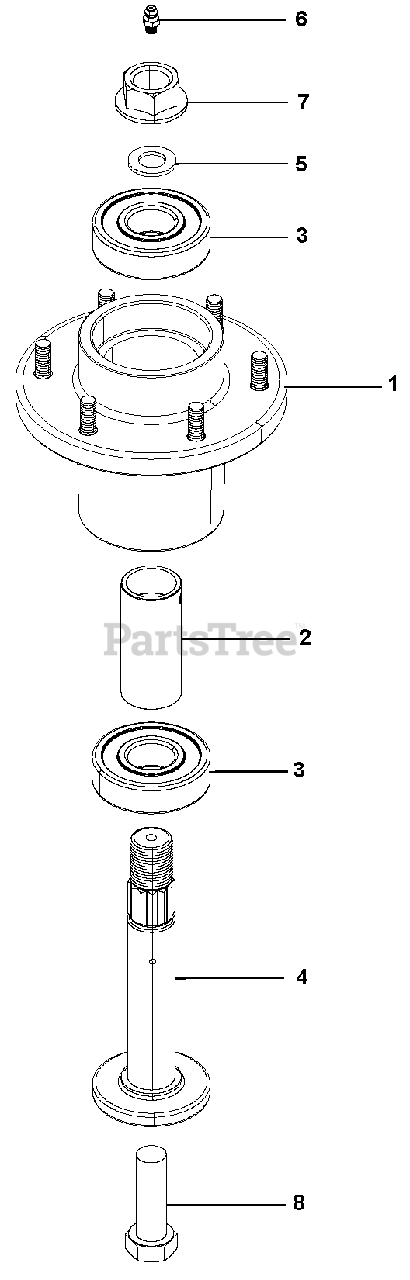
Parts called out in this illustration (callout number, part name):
1	Casting, Spindle w/Studs
2	Spacer, 1.250 x 1.000 x 2.780
3	Bearing, 6305LLC
4	Shaft, Spindle .75-16
5	Washer, .75 x 1.3125 x .120
6	Fitting, .25-28 STRGT Grease Zerk
7	Locknut, .75-16 Crown
8	Bolt, .625-11 x 2.00 Hex 8
